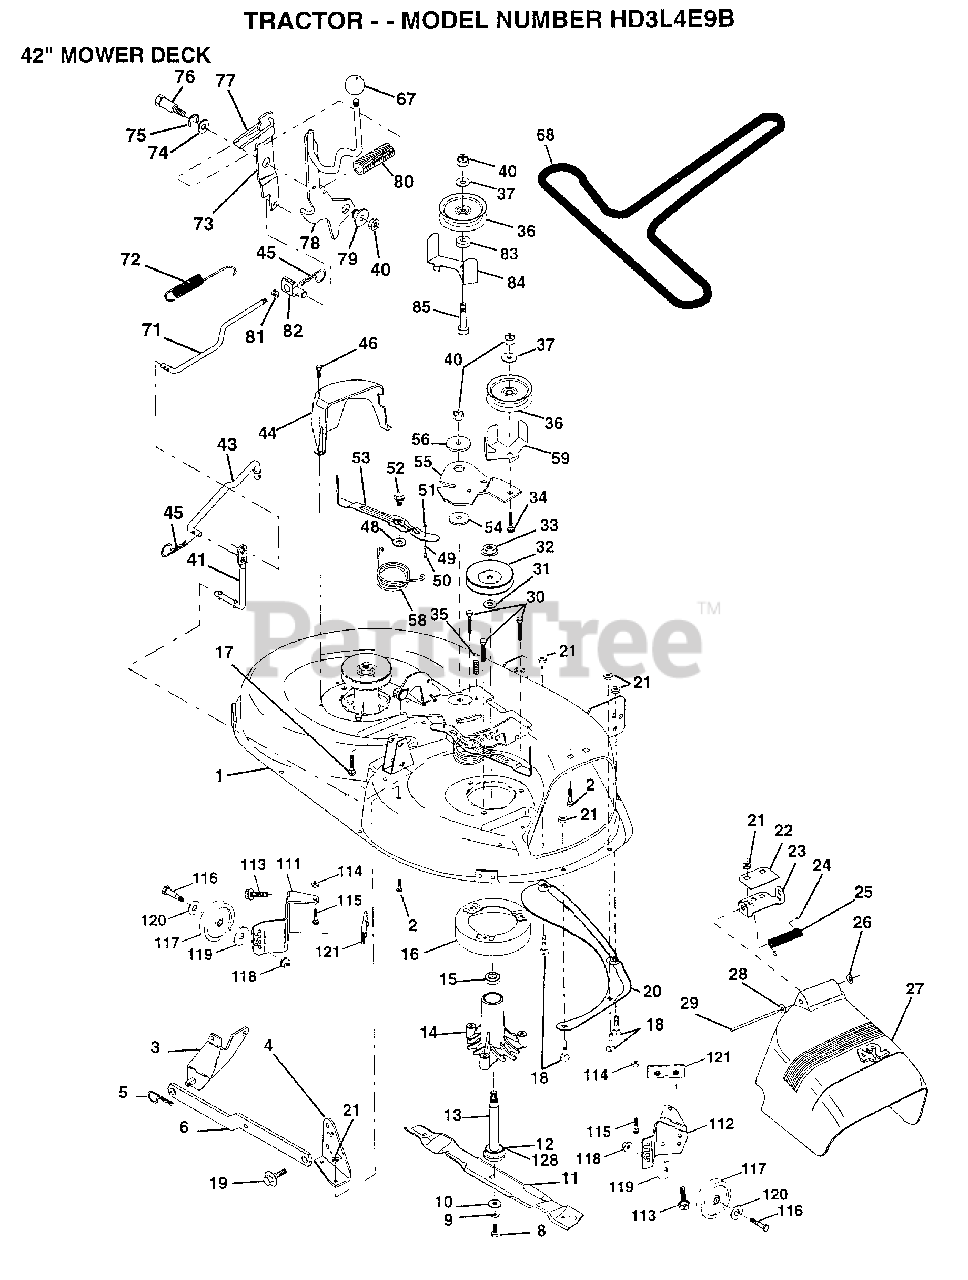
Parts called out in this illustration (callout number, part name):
1	DECK.WELD.42.
2	BOLT
3	BRKT ASM SWAY BAR
4	BRKT DECK SW BAR
8	BLADE BOLT
10	WASHER.HARD.BLADE
11	"BLADE.42"" HIPERF"
12	BEARING.BALL
14	HSG ASM MANDREL
15	BEARING
16	STRIPPER RND MWR
17	BOLT RDHD 3/8-16
18	BOLT
19	BOLT SHD 5/16-18
22	STIFFENER BRKT
23	DEFLECTOR BRKT
24	CAP-SLEEVE LT
25	SPRING TORSION
26	NUT PUSH M
27	DEFLECTOR.SHIELD
28	WASHER
29	HINGE ROD
31	WASHER
32	PULLEY.MANDREL.42
34	BOLT
35	XMAS TREE FASTNER
36	FLAT IDLER PULLEY
37	WASHER
41	PIVOT ROD
43	ROD CLUTCH W/NIBS
44	GUARD MAND LH BLK
45	RETAINER M
46	SCREW.1/4-20X5/8
48	HARD SMALL WASHER
50	SHOULDER BOLT
51	LOCKNUT
52	BOLT.SHLD.5/16-18
53	BRAKE PAD ARM ASM
54	HARDENED WASHER
56	SPACER RETAINER
58	SPRING TORSN BRAK
59	GUARD IDLER TUV
67	KNOB T (1/2-HOLE)
68	BELT.V.T-PATH
71	ROD CLUTCH 38/42
72	RETURN SPRING
73	CLUTCH ARM SECOND
74	WASHER
75	RING
76	SHOULDER BOLT
77	SPRING KEEPER
78	LEVER ASM CLT PRM
79	BUSHING
80	SPRING.CLUTCH.MWR
81	NUT
82	TRUNION ADJ
83	WASHER
85	BOLT RDHD 3/8-16
113	SCREW
116	BOLT M
117	WHEEL.GAGE.BLK.PL
118	LOCKNUT
119	WASHER
120	WASHER
121	BRACKET.EXTRD.GWL
128	WASHER.FELT.
